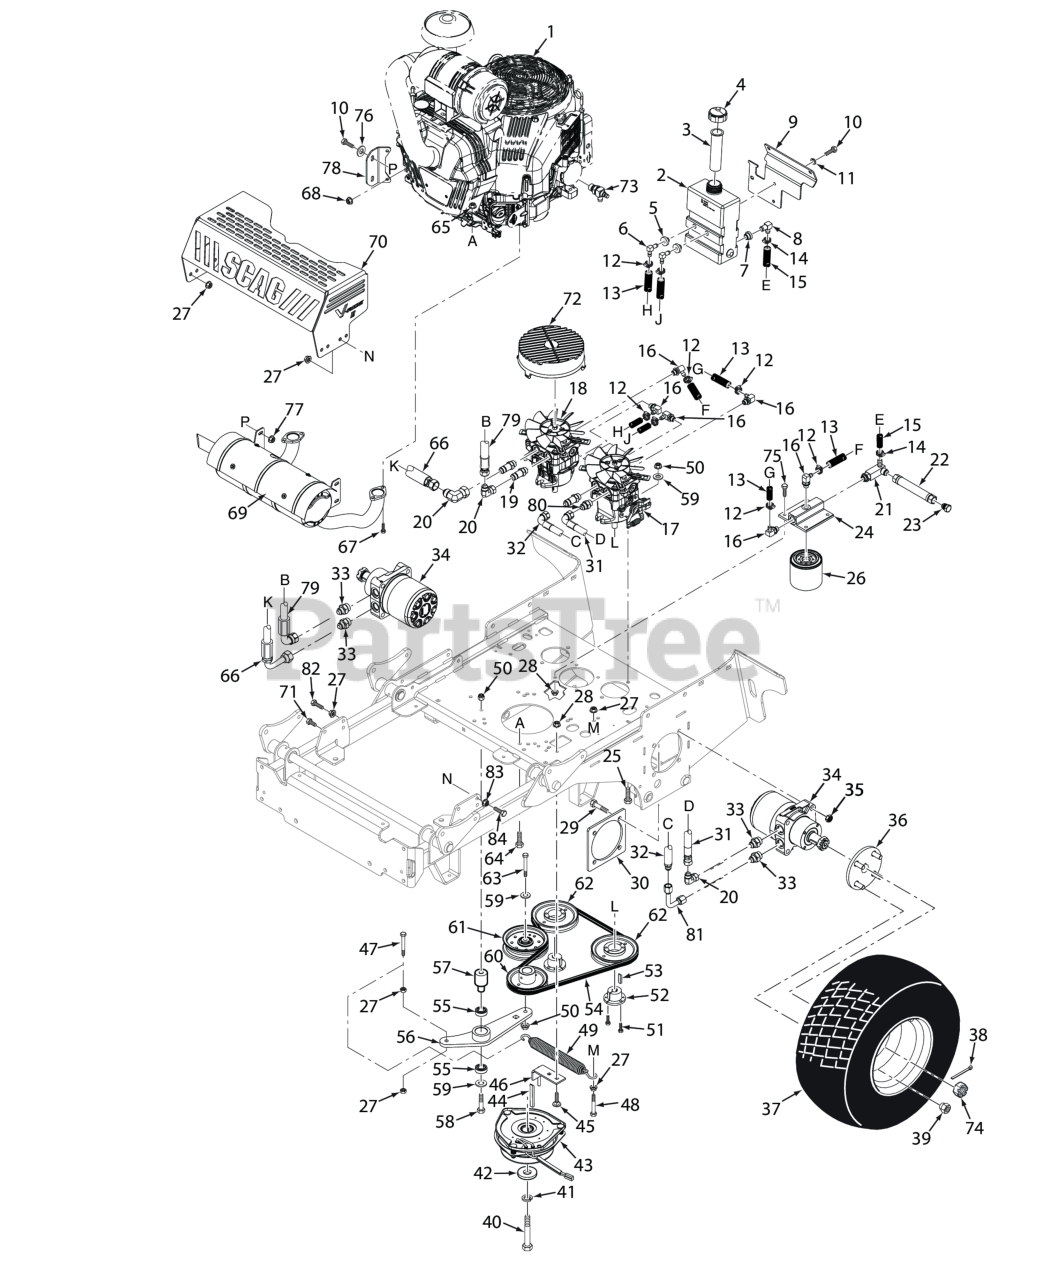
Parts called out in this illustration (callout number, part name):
1	Engine, 40 HP Vanguard EFI
2	Hydro Tank Assy., SVRII
3	Insert, Filler Neck
4	CAP, HYDRAULIC TANK
5	Bushing, 0.56" Dia. Viton
6	Elbow, 90 Degree, 9/16-18 JIC x 9/16 O-Ring
7	Bushing, 0.78" Dia. Viton
8	Fitting, 90 Degree - 1/2" Hose
9	Bracket, Hydro Tank Mounting
10	BOLT, SERRATED FLANGE HEX HEAD 5/16-18 X 3/4"
11	Lockwasher, 5/16 (.317 x .586 x .078) Helical Spring
12	Clamp, .69" Max. / .25" Min. Dia.
13	Hose, 3/8" ID - 10-1/4" Long (Order By The Inch)
14	Clamp, Cable 3/4" I.D.
15	Hose Assembly, 1/2" ID (Oil Reservoir to Filter Base)
16	Elbow, 90 Degree - 9/16" O-Ring x 3/8" Hose
17	Pump, LH - SVRII
18	Pump, RH - SVRII
19	Union, O-Ring to JIC
20	Elbow, 1/2 JIC Female to 1/2 JIC Male
21	Tee, 3/4" O-Ring
22	Drain, Hose Assembly
23	Plug, JIC 3/4-16 UNF
24	Filter Head Assembly
25	Bolt, Hex Head, 3/8-16 x 1-1/2"
26	OIL FILTER, SPECIAL
27	NUT, 3/8-16 SERRATED FLANGE HEX HEAD
28	Nut, Serrated Flange 5/16-18 (Right Front Engine Mounting, Briggs and Kohler Only)
29	Bolt, Hex Hd. 1/2-13 x 2-1/2" (lower)
30	Plate Weldment, Motor Backing
31	Hose Assembly
32	Hose Assy., 18-1/2"
33	TUBE UNION, 3/4-16 JIC TO 7/8-14 "O" RING
34	Wheel Motor, Parker
35	Locknut, Hex 1/2-13 Center Lock
36	Wheel Hub Assy., SVRII
37	Wheel Assembly, 24 x 12-12 (SPZ61)
38	Pin, Cotter 9/16" x 1-1/2"
39	Wheel Nut, 1/2-20 x 13/16
40	Bolt, Hex Head 7/16-20 x 2-1/4" w/Patch (Kawasaki)
41	Lockwasher, 7/16� Spring
42	Flatwasher, 7/16-.469 x 1.75 x .25 (48, 52)
43	Clutch w/Tag GT3.5--FE05 (61)
44	Key, 1/4 x 1/4 x 3-1/2"
45	Bolt, 5/16-18 x .75 RHSN Carriage
46	ANTI-ROTATION WLMT, SVRII
47	Bolt, Hex Head 3/8-16 x 1-1/2" Grade 8 Black
48	Bolt, Hex Head 3/8-16 x 3" - 52"
49	Spring, Transmission Drive
50	HEX NUT, ELASTIC STOP LOCK, 3/8-16
51	Bolt, Hex Head 1/4-20 x 1" Grade 8 Black
52	Hub, Tapered, 15mm Bore
53	KEY, 5 MM X 5 MM X 25 MM
54	Belt, Pump Drive (37BV-EFI)
55	BEARINGS, BALL, NEUTRAL RETURN
56	Idler Arm Assy.
57	Pivot, Idler
58	Capscrew, Hex Head 3/8-16 x 3.25"
59	Flatwasher, 3/8 (.391 x .938 x .105 HD) Grade 8
60	Pulley, 4-3/4" OD - 1.125 Bore
61	Pulley, Idler 4-1/2"
62	Pulley, 5.45 OD - Tapered Bore"
63	Bolt, Hex Head 3/8-16 x 2-1/4" - 61"
64	Bolt, Hex Head, 3/8-16 x 1-1/2"
65	Nut, Flanged Top Lock 3/8-16
66	Hose Assy., 15-1/4"
67	Bolt, Hex Head M8 - 1.25 x 20
68	Nut, M6-1.0 Hex Flange
69	Muffler, Vanguard 37 EFI - SVRII
70	Heatshield, Muffler- SVRII
71	Bolt, Hex Head, 3/8-16 x 3/4"
72	Fan Cover, Pump
73	Oil Drain, 35BV & 37BV-EFI - Briggs & Stratton
74	Nut, Hex Castle 1.0-20 UNEF
75	Bolt, Heax Head 5/16-18 x 1" (48V / 52V)
76	Flatwasher, 5/16-.375 x .875 x .083 (35BV & 37BV-EFI)
77	Nut, Flange Head Elastic Stop 5/16-18
78	Bracket, Muffler Mount
79	Hose Assy., 27-1/2"
80	Union, 3/4"-16 JIC x 3/4"-16 O-Ring
81	Tube Assy.
82	Bolt, Hex Head 3/8-16 x 1-1/2" Grade 8 Black
83	NUT, 3/8-16 SERRATED FLANGE HEX HEAD
84	Bolt, Hex Head 3/8-16 x 1-1/2" Grade 8 Black
